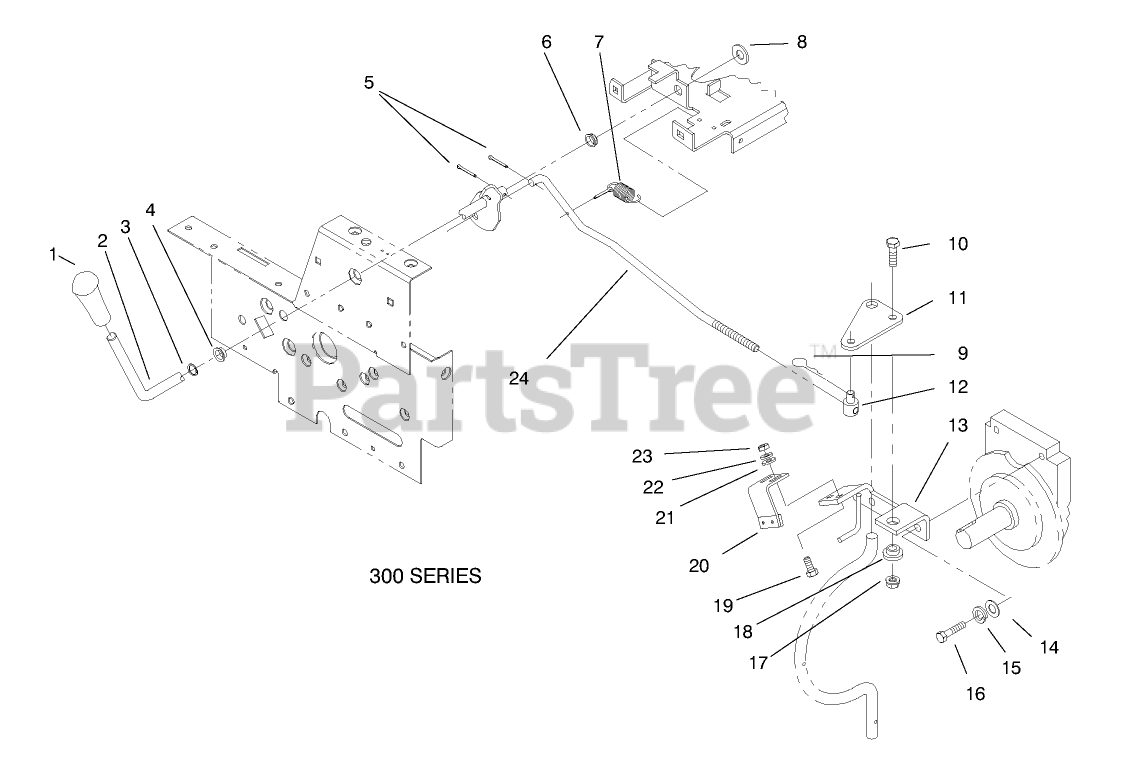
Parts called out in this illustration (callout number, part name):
2	PTO CLUTCH LEVER ASM
3	RING-EXT GRIP
4	BUSHING-NYLINER
5	PIN-COTTER
6	BUSHING-NYLINER
7	SPRING
8	SHIM-WASHER
9	PIN-HAIR
10	SCREW-HH
11	PLATE
13	ENGINE SUPPORT ASM
14	WASHER-FLAT
15	WASHER-LOCK
16	SCREW-HH
18	SPACER-LIFT LINK
20	BRAKE ASM
21	WASHER-FLAT
22	WASHER-LOCK
23	NUT-JAM
24	ROD-PTO CLUTCH
